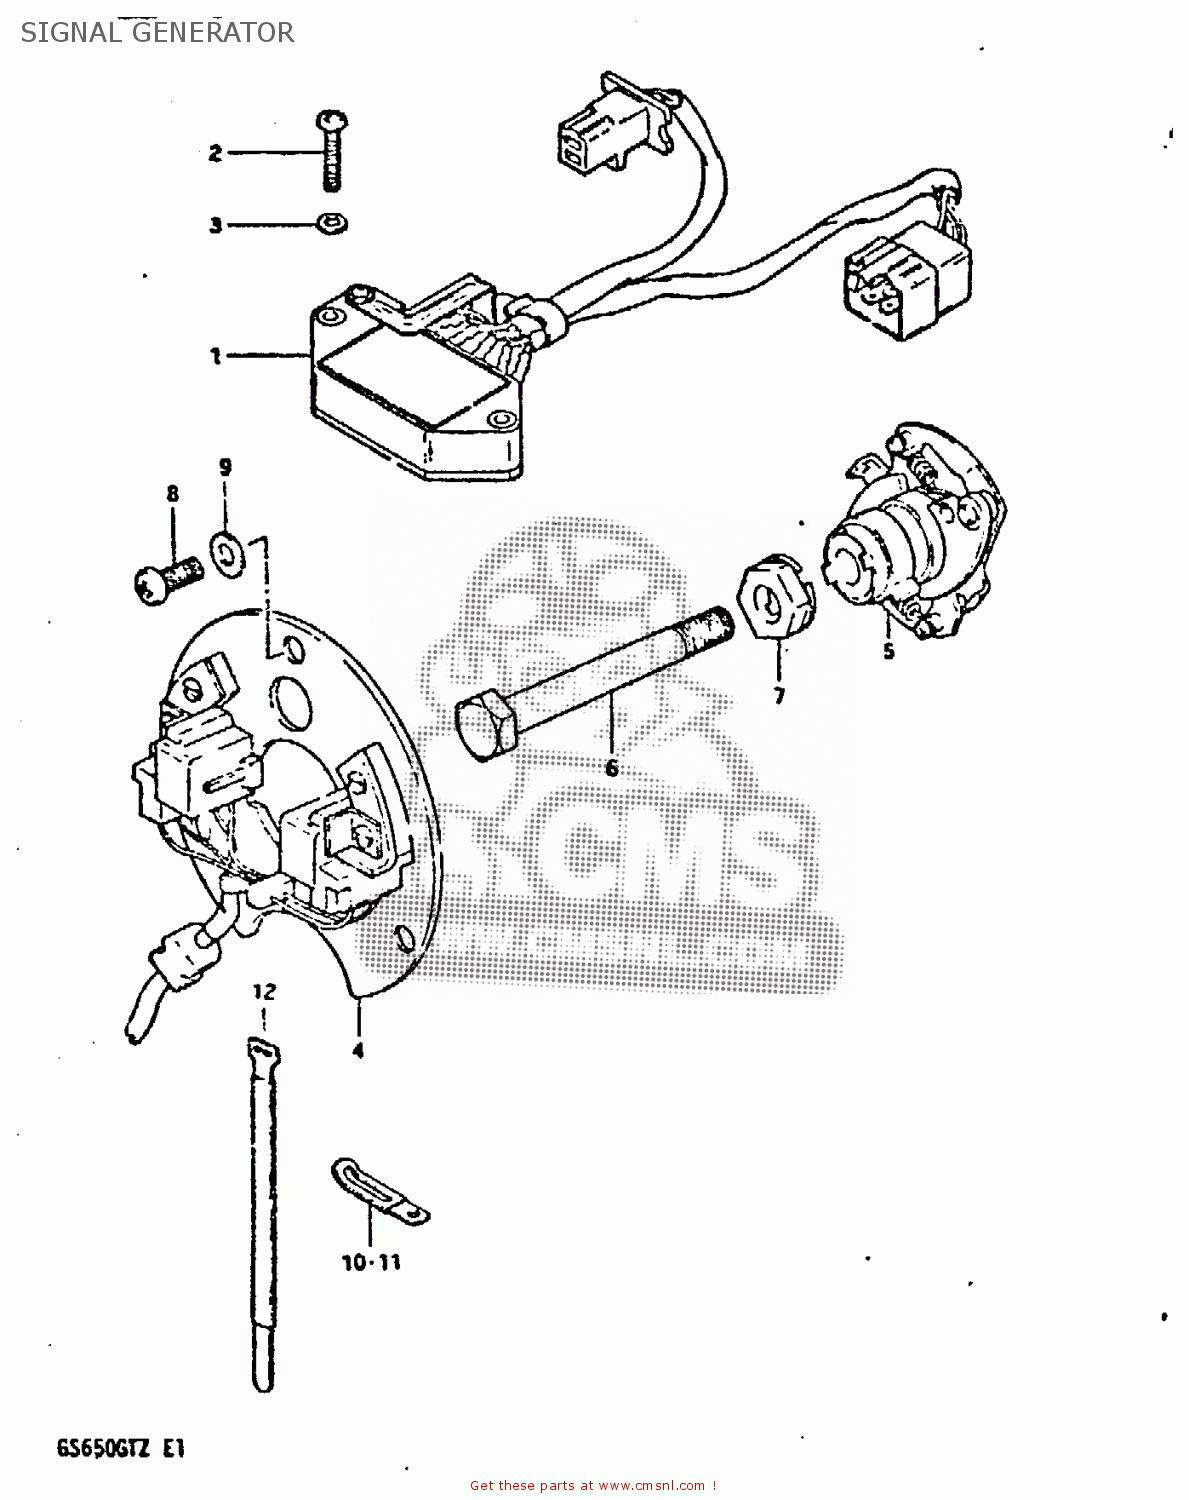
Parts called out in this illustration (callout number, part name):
1	IGNITER UNIT ASSEMBLY
2	SCREW
3	WASHER
4	SIGNAL GENERATOR ASSEMBLY
5	GOVERNOR ASSEMBLY
6	BOLT
7	WASHER
8	SCREW(5X12)
9	WASHER
10	CLAMP L:35
11	CLAMP
12	CLAMP
